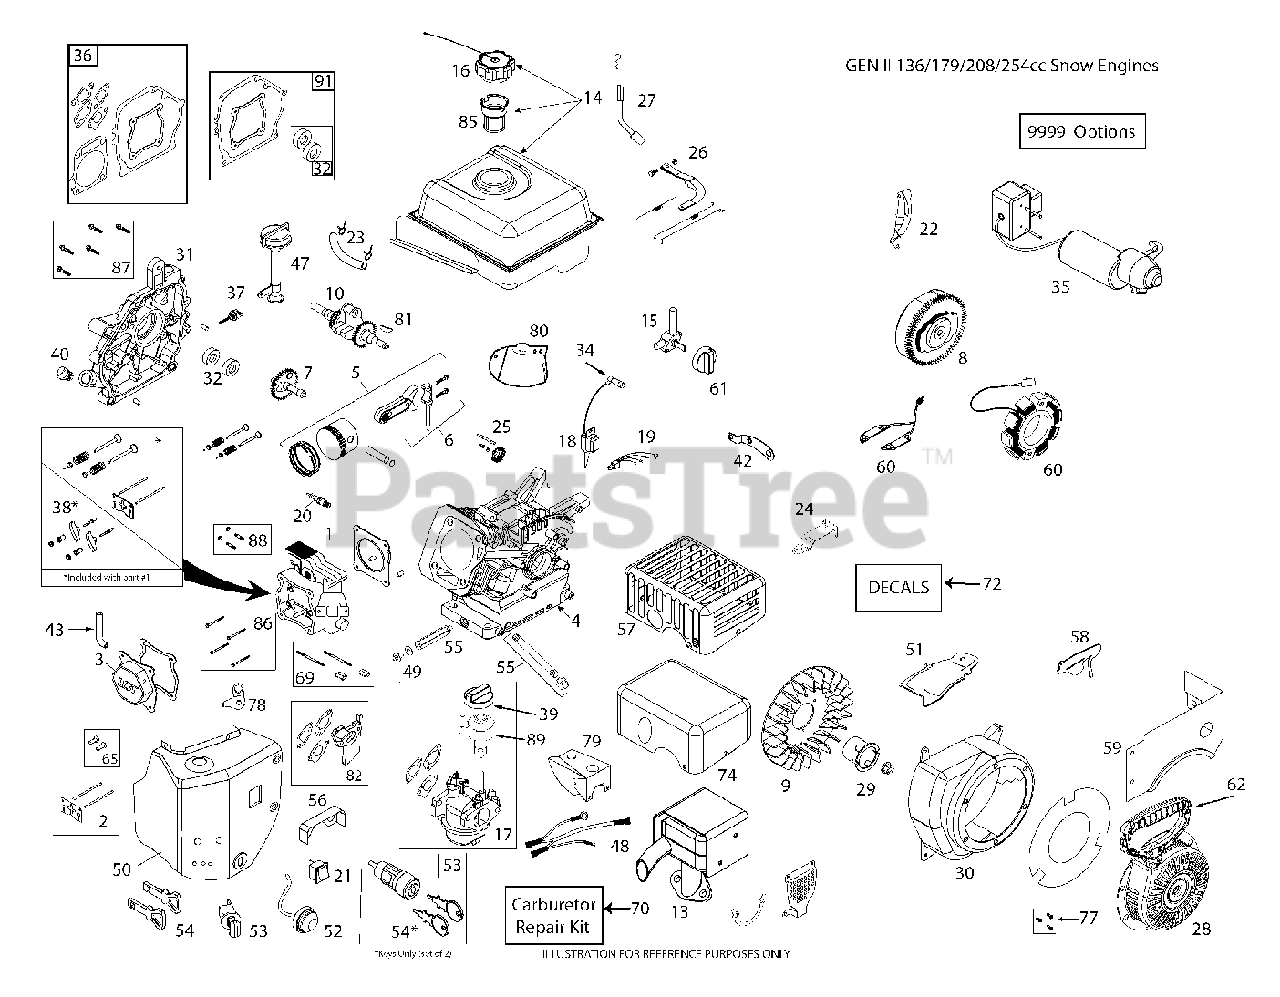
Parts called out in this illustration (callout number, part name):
1	CYLINDER.HEAD.ASM.W/GASKET.254
2	KIT.PUSH.ROD.&.PLATE.W/VC.GASK
3	COVER.VALVE.W/GASKET.254CC
4	CYLINDER LCT 254 FT OIL DRAIN
5	PISTON.&.ROD ASSEM.254CC
6	Husqvarna TBD
7	CAMSHAFT.MCR.W/GASKET.254CC
8	FLYWHEEL.ELEC.STRT.(8.MAGNETS)
9	KIT.COOLNG.FAN.SERV(SK208-4000
10	CRANKSHAFT.KEYED(#18).SNOW.254
13	MUFFLER.ASSEM.GEN2.SNOW.254CC
14	FUEL.TANK.SNOW.2.7L.BLACK.254C
15	FUEL.PETCOCK.SNOW(SKSN4900)
16	FUEL CAP OVERSIZED CLICK STYLE
17	CARBURETTOR LCT 254 W/IDLEDOWN
18	COIL.ING.CDI.HI TEMP.SKSNO416.
19	Husqvarna TBD
20	PLUG.SPARK.PLAT.SKSN2404.1
21	SWITCH.ON/OFF(SKSN-0403)
22	SHIELD.FLYWHEEL.ELEC.STRT.208C
23	FUEL HOSE KIT
24	BRACKET.SPEED.CNTRL.FIXED.254C
25	GOVENOR.GEARS ASM(SK2082900)
26	KIT.GOVERNOR.ARM.&.LINK.254CC
27	KIT.GOVERNOR.CRANK(SK208-3100)
28	RECOIL.STRT.ROUND(BLK) SNOW
29	STRTER.CUP(NON-SLOT)SKSN0601.2
30	BLOWER HSG.LCT 254 GLOSS BLK S
31	CRANKCASE.CVR.PRESS.IN.HI-OIL.
32	KIT.SEAL.OIL.2.PIECES.254CC
34	SPARK.PLUG.BOOT.SNW,SKSN4691.1
35	ELEC.START.GEN2.SKSN0451.1
36	KIT.ENGINE.GASKET.254CC
37	Husqvarna TBD
38	KIT.ROCKER.ARM.W/GASKET.254CC
39	CHOKE.KNOW.SNOW(SKSN4500)
40	NON REMOVABLE PLUG
42	Husqvarna TBD
43	TUBE.BREATHER.LCT.208
47	TUBE ASSY HIGH OIL-FILL
48	WIRE.HARNESS.SNOW
49	KIT.OIL.DRAIN.PLUG(SK2089911
50	KIT.HEATER.BOX.SNOW.254CC
51	Husqvarna TBD
52	PRIMER.BULB.WITH HOSE (SNOW)
53	SWITH.KEY.ASSEM.SNOW.SINGLE.ST
54	KEY SET(2 KEYS) SKSN0407.1
55	OIL PIPE DRAIN LCT 254
56	SHIELD.CARBURETOR.VAPOR
57	Husqvarna TBD
58	SHIELD.GOVERNOR.LINKAGE.254CC
59	FUEL TANK SKIRT SHIELD LCT 254
60	208CC 60W ALTERNATOR
61	FUEL KNOB-SNOW
62	HANDLE.RECOIL.DELUXE.LCT
65	TAPPET.KIT.LCT.208CC
69	CARB.STUDS & COUPLING KIT.SNOW
70	CARB.REPAIR.KIT.LCT.SK9900.2
72	Husqvarna TBD
74	COVER.MUFFLER.HEAT.SHIELD.
77	BOLT.KIT.RECOIL.LCT.ALL.ENGINE
78	Husqvarna TBD
79	COVER.CARBURETOR.SNOW
80	SHIELD.GOVERNOR.LINK.SNOW.254C
81	KEYS.FLYWHEEL.136/291CC.5PACK
82	SPACER.CARBURETOR.208CC.LCT
85	STRAINER.FUEL.TANK.LCT.208CC
86	KIT.BOLT.CYLINDER.HEAD.(4PC)
87	KIT.BOLT.CRANKCASE.COVER.6PC
88	STUD.MUFFLER.KIT.LCT
89	KNOB LCT.SKSN5325.1 SPEED
91	CRANKSHAFT GASKET KIT.LCT
9999	JET HIGH ALTITUDE LCT 5000 25
9999	KIT.BOLT.LCT.SK9990.1
